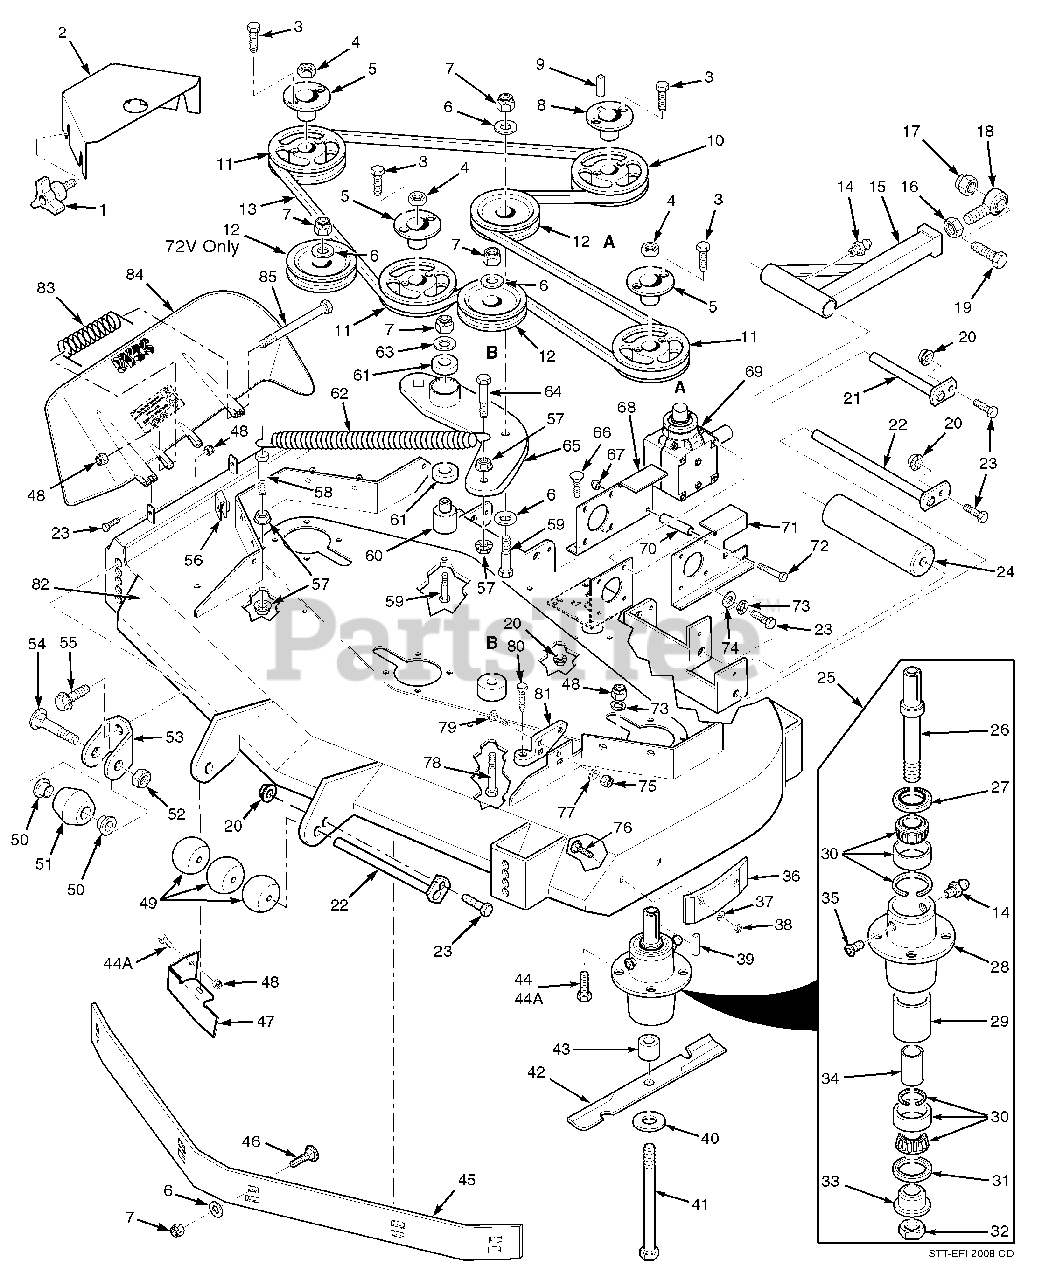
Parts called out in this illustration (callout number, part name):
1	Wing Nut, 3/8-16
2	Belt Cover
3	Bolt, Hex Head 1/4-20 x 1” Grd 8
4	Nut, 5/8-11 UNC
5	Tapered Hub, 1-1/8” Bore
6	Flatwasher, 3/8”
7	Nut, Hex Elastic Stop 3/8-16
8	Tapered Hub, 1” Bore
9	Key, 1/4 x 1/4 x 1-1/4”
10	Pulley, 6.75 O.D.
11	Pulley, 5.75 O.D.
12	Pulley, Idler
13	Belt, Cutter Deck Drive
14	Grease Fitting
15	Pusharm
16	Nut, Hex Head 5/8-18 UNF
17	Nut, Hex Elastic Stop 5/8-11
18	Rod End, 5/8” Male RH Thread
19	Bolt, Hex Head 5/8-11 x 4-1/2”
20	Nut, Hex Serrated Flange 5/16-18
21	Push Arm Shaft
22	Roller Shaft
23	Bolt, Hex Head 5/16-18 x 1-3/4”
24	Wheel, Anti-Scalp
25	Spindle Assembly
26	Spindle Shaft
27	Seal, Top
28	Spindle Housing
29	Spacer, Outside
30	Bearing Assembly
31	Seal, Bottom
32	Nut, Special 1-1/16-18
33	Spindle Bushing, Bottom
34	Spacer, Inside
35	Relief Fitting, Tapered Spindle
36	Wear Pad
37	Flatwasher, 5/16”
38	Nut, Center Lock 5/16-18
39	Key, 1/4 x 1/4 x 2”
40	Flatwasher, 5/8” Hardened
41	Bolt, Hex Head 5/8-11 x 9-1/2”
42	Cutter Blade, 21”
43	Spacer, Spindle Bottom
44	Bolt, Hex Head 5/16-18 x 1-3/4”
45	Baffe, Custom Cut 61V
46	Bolt, Carriage 3/8-16 x 1”
47	Discharge Baffe 61V
48	Nut, Hex Elastic Stop 5/16- 18 Grd 8
49	Wheel, Anti-Scalp
50	Bushing, .376 I.D. Oilite
51	Anti-Scalp Wheel
52	Locknut, 3/8-16 Center Lock
53	Anti-Scalp Wheel Bracket
54	Bolt, Carriage 3/8-16 x 4”
55	Bolt, Hex Serrated Flange 3/8-16 x 1”
56	U-Nut, 3/8-16
57	Nut, Hex Serrated Flange 3/8-16
58	Bolt, Hex Head 3/8-16 x 1-1/2”
59	Bolt, Hex Head 3/8-16 x 3”
60	Pivot, Idler - Short
61	Bearings, Ball
62	Spring, Cutter Deck
63	Flatwasher,3/8-.39 x .938 x .105 HD
64	Bolt, Hex Head 3/8-16 x 1-1/2” Grd 8
65	Idler Arm, Cutter Deck
66	Bolt, Carriage 5/16-18 x 3/4”
67	Nut, Elastic Stop 5/16-18
68	Mounting Plate, RH Gearbox
69	Gearbox Assembly, Deck Drive
70	Spacer, Gearbox Mount
71	Mounting Plate, LH Gearbox
72	Bolt, Hex Head 5/16-18 x 4-3/4”
73	Lockwasher, 5/16”
74	Flatwasher, 5/16”
75	Nut, Elastic Stop 7/16-14
76	Bolt, Carraige 5/16-18 x 3/4”
77	Flatwasher, 7/16-.500 x 1.25 x .083
78	Bolt, Hex Head 3/8-16 x 3-1/4”
79	Bolt, Carriage 7/16-14 x 1-1/4”
80	Bolt, Deck Adjust
81	Lever Assy, Deck Level
82	Cutter Deck 61 V w/Decals
83	Spring, Discharge Chute
84	Discharge Chute 61V
85	Bolt, Hex Head 5/16-18 x 4-1/2”
